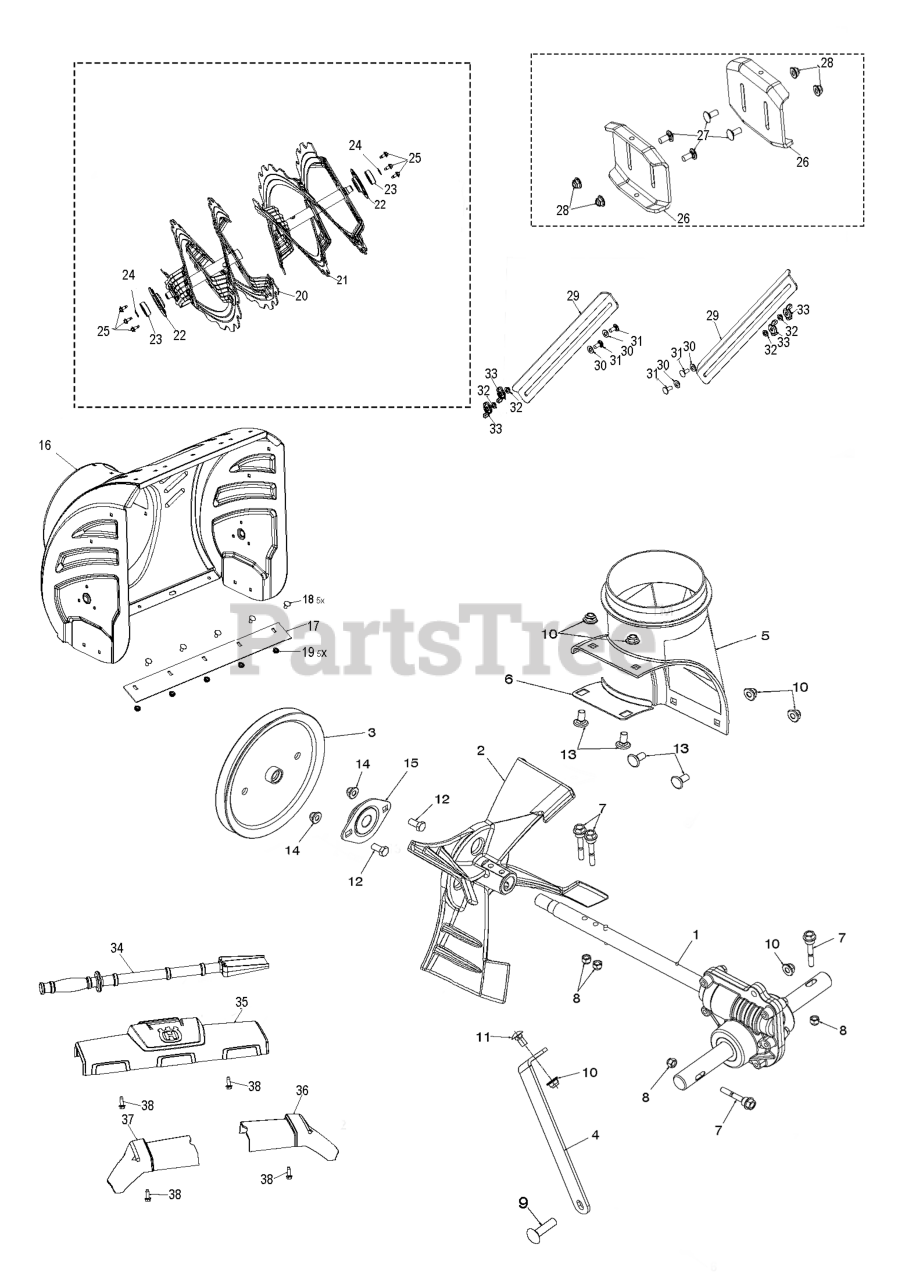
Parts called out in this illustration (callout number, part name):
1	GEAR BOX ASM CAST
2	IMPELLER CAST.IRON.12IN MS 417
3	PULLEY SCREW ON 7.9
4	SUPPORT.GEARBOX.LS.498
5	CHUTE.DISCHARGE.BASE
6	BRACKET, CORNER DISCHARGE
7	BOLT.1/4-20 X 1-13/16 SHEAR
8	LOCKNUT.NYLOC.1/4-20
9	BOLT.CARRIAGE.5/16-18
10	NUT HEX FLG NYLOCK BLK 5_16-1
11	BOLT CAR BLK 5/16-18 X 5/8
12	BOLT, HEX HEAD 5/16-18
13	BOLT CARR WAFER BLK 5_16-18 X
14	NUTNYLOK.FLRANGE.5/16-18
15	BEARING FLANGE
16	KIT.AUGR.HSG.581976702(24LS668
17	PLATE.SHAVE.24.LS.SNOW.BLACK
18	BOLT
19	NUT.FLANGE.5/16
20	AUGER.RIBBON.24.RH.LS.479
20	AUGER.RIB.24.RH.LS.GREY
21	AUGER.RIBBON.24.LH.LS.479
21	AUGER.RIB.24.LH.LS.GREY
22	SUPPORT.BEARING.SINGLE.STAGE.B
23	BEARING.BALL.MANDREL
23	BEARING
24	RETAINING RING LT
25	HEX.WASHER.HEAD 1/4-20 X .65
26	SKID PLATE
27	BOLT CARR BLK 5_16-18 X .750
28	NUT HEX FLG NYLOCK BLK 5_16-1
29	DRIFT CUTTER BAR
30	WASHER, NYLON FRICTION
31	BOLT
32	WASHER.LOCK.HVY.HLCL.SPR.5/16
33	NUT WING PM
34	CLEAN OUT TOOL
35	TRIM AUGER.HOUSING.FRONT.ASM
36	TRIM AUGER.HOUSING.WING.RH MS
37	TRIM AUGER.HOUSING.WING.LH MS
38	SCREW HEXWSHR 1/4-20X3/4
